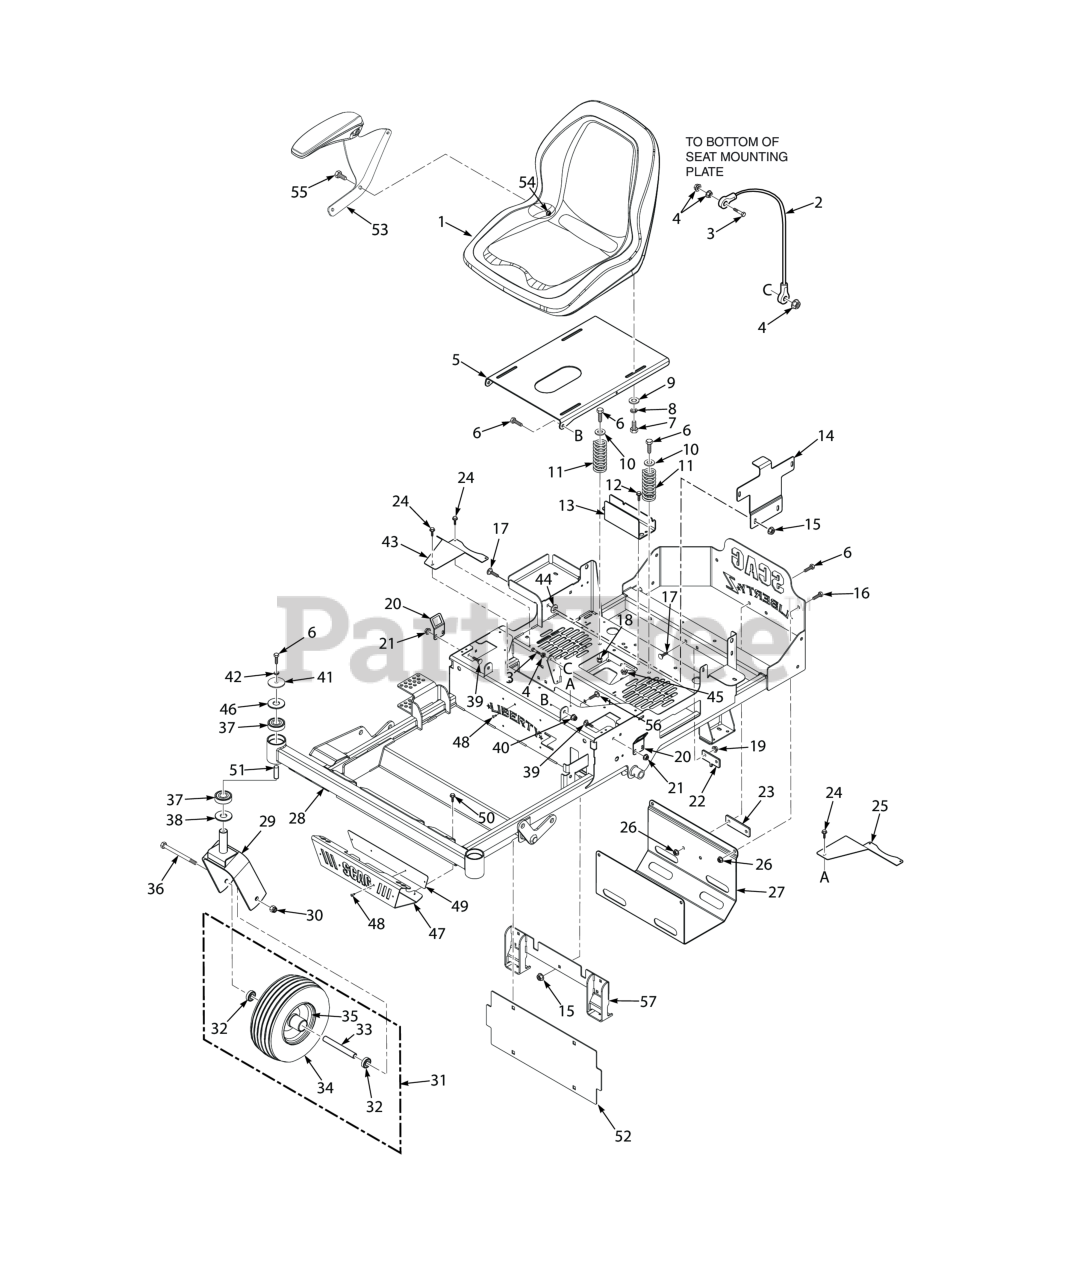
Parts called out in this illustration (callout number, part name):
1	Seat, SZL w/Armrests
2	Cable, Seat Stop
3	SERR. FLG. HEX HEAD CAPSCREW, 5/16-18 X 3/4
4	NUT, 1/4-20 SERRATED FLANGE HEX HEAD
5	Seat-Plate W/Decal
6	Bolt, Hex Head, 3/8-16 x 1 Gr. 5
7	Bolt, Heax Head 5/16-18 x 1" (48V / 52V)
8	Lockwasher, 5/16 (.317 x .586 x .078) Helical Spring
9	Flatwasher, 5/16-.375 x .875 x .083 (35BV & 37BV-EFI)
10	Flatwasher, 3/8" Special (.391 x .938 x .105)
11	Spring, Seat
12	Capscrew, 5/16-18 x .75 Serrated Flange Hex Head
13	Channel, Hose
15	Nut, Flange Head Elastic Stop 5/16-18
16	Bolt, Hex Head, 3/8-16 x 3/4"
17	Bolt, 5/16-18 x .75 RHSN Carriage
18	HEX NUT, ELASTIC STOP LOCK, 3/8-16
19	Nut, Flange Head Elastic Stop 5/16-18
20	Bracket, Switch
21	Nut, Flanged Elastic Stop 1/4-20
22	Plate, Anti-Rotation
23	Plate, Spacer
24	Screw, #10-32 x .563 Shakeproof
25	Guard, Belt - LH
26	NUT, 3/8-16 SERRATED FLANGE HEX HEAD
27	Skid Plate, SZL
28	Mainframe w/Decals - SZL48H/52H
29	Caster Assembly
30	HEX LOCKNUT, ELASTIC STOP, 1/2-13
31	CASTER WHEEL ASSY, 11.00 X 6.00-5
32	Bearing
33	SPACER, WHEEL BEARING
34	TIRE, 11 X 6.00-5
35	RIM ASSY, 5 X 3 W/5.625 LG HUB
36	Bolt, Hex Head 1/2-13 x 7-1/2" (48"/52")
37	Bearing
38	Spacer, Yoke
39	Serr. Fl. Hex Head CPSCR, 1/4-20 x 3/4"
40	Nut, Flange Elastic Stop Nut, 3/8-16
41	Flatwasher, 3/8-.406 x 2.25" x .1875
42	Lockwasher, 3/8" Spring, Kawasaki FX / FS
43	GUARD, BELTS - RH
44	Nut, Push-On 5/16-18
45	Nut, Serrated Flange 5/16-18 (Right Front Engine Mounting, Briggs and Kohler Only)
46	Flatwasher, 7/16" (.500 x 1.25 x .083")
47	Bumper. Front
48	Rivot, 3/16 x .402 POP
49	Plate, Decal
50	Screw, 1/4-20 x .375"
51	Spacer, Caster Bearing
52	Plate, Backing
53	Armrest, RH (48H, 52H, 61H)
54	SPEED U-NUT,1/4-14
55	SCR,HHSCR, 1/4-14 X1 TYPA THRD FRMNG
56	Bolt, 5/16-18 x .75 RHSN Carriage
57	Mounting Weldment, Axle - Tuff Torq
